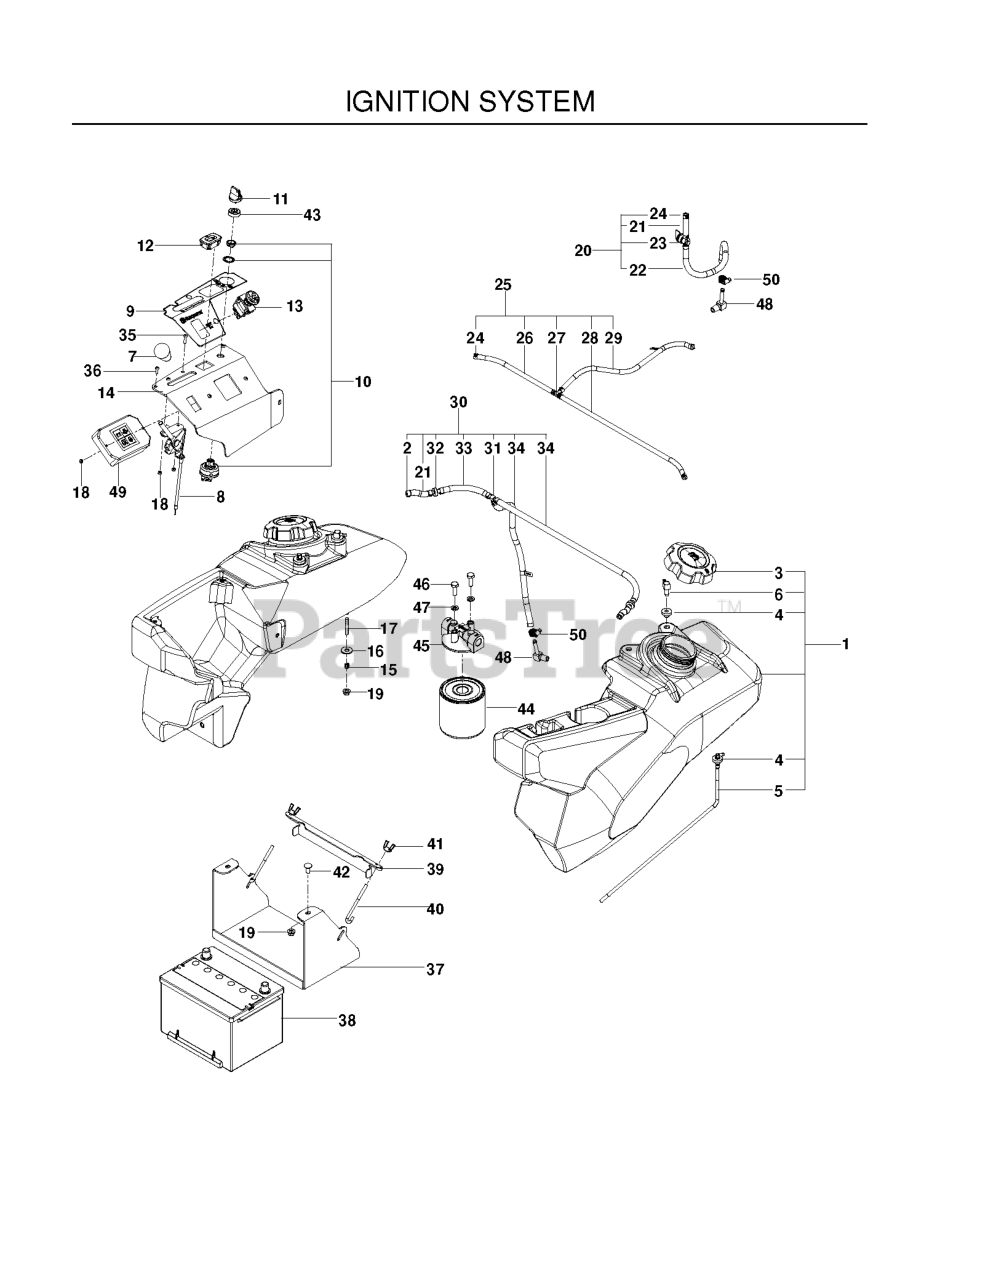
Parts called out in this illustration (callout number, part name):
1	FUEL TANK LT DIESEL
2	CLAMP, HOSE
3	CAP, DIESEL FUEL
4	RUBBER GROMMET
5	FITTING, FUEL
6	FITTING, RETURN, 90
7	KNOB - SHIFT
8	CABLE, THROTTLE, DIESEL
9	DECAL, CONTROL, DIESEL
10	SWITCH, IGNITION, INDAK
11	KEY, IGNITION
12	HOUR METER
13	SWITCH, PTO 10 AMP
14	PANEL, CONTROL, DIESEL-GRAY
16	FLAT WASHER 5/16 SAE
17	STUD, 5/16C
18	NUT 10-24 NYLOC
19	5/16-18 NYLOC FLANGE NUT
20	LINE, FUEL ASSEMBLY
21	FUEL LINE 3"
22	FUEL LINE 14"
23	FUEL VALVE
24	HOSE CLAMP
25	ASSEMBLY, FUEL LINE, RETURN
26	HOSE, FUEL, 3/16" X 9-1/2"
27	TEE, FUEL LINE 3/16"
28	HOSE, FUEL, 3/16" X 17-1/4"
29	HOSE, FUEL, 3/16" X 18-1/2"
30	ASSEMBLY, FUEL LINE
31	TEE, FUEL LINE, .25
32	VALVE, CHECK, .25
33	FUEL LINE 5"
34	HOSE, FUEL 1/4" X 21"
35	SCR #10-24 X .75 SKT HD BLK
36	SCR #10-24 X 3/8 SKT HD BLK OX
37	BOX, BATTERY, BLK
38	BATTERY, 500 CCA
39	BRACKET, BATTERY MOUNT
40	HOOK, "J"
41	WING NUT 1/4
42	BOLT 5/16C X 3/4" CARRIAGE
43	CAP IGNITION NUT
44	FILTER, FUEL
45	HEAD, FUEL FILTER
46	HCS 1/4C X 3/4 HCS
47	LOCKWASHER 1/4"
48	FITTING, FUEL, 90
49	MODULE, CONTROL
50	CLAMP, WORM GEAR, NO. 4
